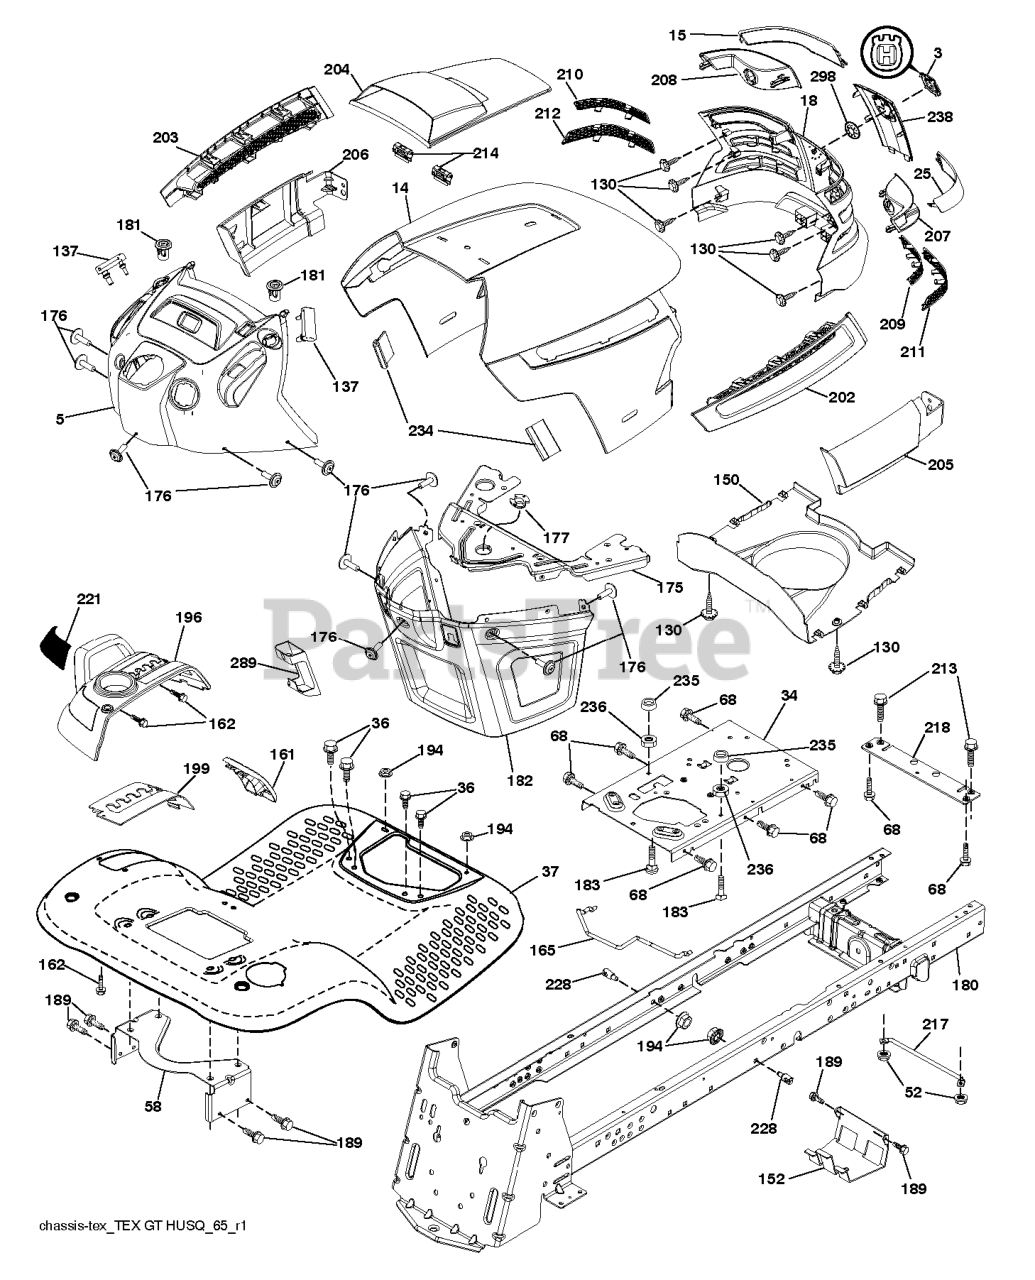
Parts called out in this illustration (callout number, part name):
3	RP LOGO
14	HOOD
15	LENS.LH.TEX.GT.HUSQ.CL
18	GRILL.ASM.HUSQ.TG/CRD.W/TRIM
25	LENS.RH.TEX.GT.HUSQ.CL
34	PLATE.ENGINE.WELDED.CHASSIS
36	SCREW 5/16"
37	FENDER.PNT.TX.GT.CH/FW.ORANGE
52	LOCKNUT
58	BRKT.SUPPORT.FNDR/TANK
68	Screw 5/16-18 x 1/2 Hex, Self Tapping 5/16-18 x 1/2
130	SCREW.#10 X 0.750.BOS
137	BUMPER DASH
150	AIR.DUCT.HOOD.TEX.GT.HUSQ
152	SHIELD.BROWNING.W/TEX
161	CONSOLE.FUEL.WINDOW.HU
162	SCREW.HI-LO.CONSOLE
165	SUPPORT.TANK.REAR.W/TEX
175	PLATE.CROSSMEMBER.HUSQ
176	SCREW.#10-24X5/8.RN.QU
177	BUSHING, STEERING
180	CHASSIS.GT.SLOPED.DRAWBAR.
181	BUSHING.MNT.FEND.CRGO.
182	DASH.LOWER.COMMON.12V.ADAPTOR
183	BOLT.5/16-18X1-1/4 FULL.THREAD
189	SCREW
194	NUT LOCK HEX FLANGE 5/16-18
196	RP CONSOLE.ASM.DECKLFT.W/
199	PLATE.DECK.LIFT.HUSQVARNA.GT
202	VENT.SIDE.HOOD.HUSQ.RH.GREY
203	VENT.SIDE.HOOD.HUSQ.LH.GRAY
204	HOOD VENT
205	SKIRT.HOOD.SIDE.HUSQ.RH.GREY
206	SKIRT.HOOD.SIDE.HUSQ.LH.GREY
207	BEZEL.RH.TEX.GT.HUSQ
208	BEZEL.LH.TEX.GT.HUSQ
209	INSERT.HEX.GRILL.HUSQ.GREY
210	INSERT.HEX.GRILL.HUSQ.
211	INSERT.HEX.GRILL.HUSQ.
212	INSERT.HEX.GRILL.HUSQ.
213	BOLT
214	CLIP.RETAINER.TINNER.
217	ROD.PIVOT.HOOD
218	X-PIECE.HOOD.STOP.NON/
221	REFLECTOR.LH.TEX GT HU
228	STUD.FASTNER.W/ANTI-ROTATE
234	BUMPER.HOOD.TEX.HUSQVARNA
235	SPACER FENDER
236	NUT.CENTERLOCK.5/16-
238	TRIM.HUSQ.TG/CRD.SERVICE
289	PLUG.N/CRUISE.COMMON.YT/GT.BLK
298	NUT PUSH M
